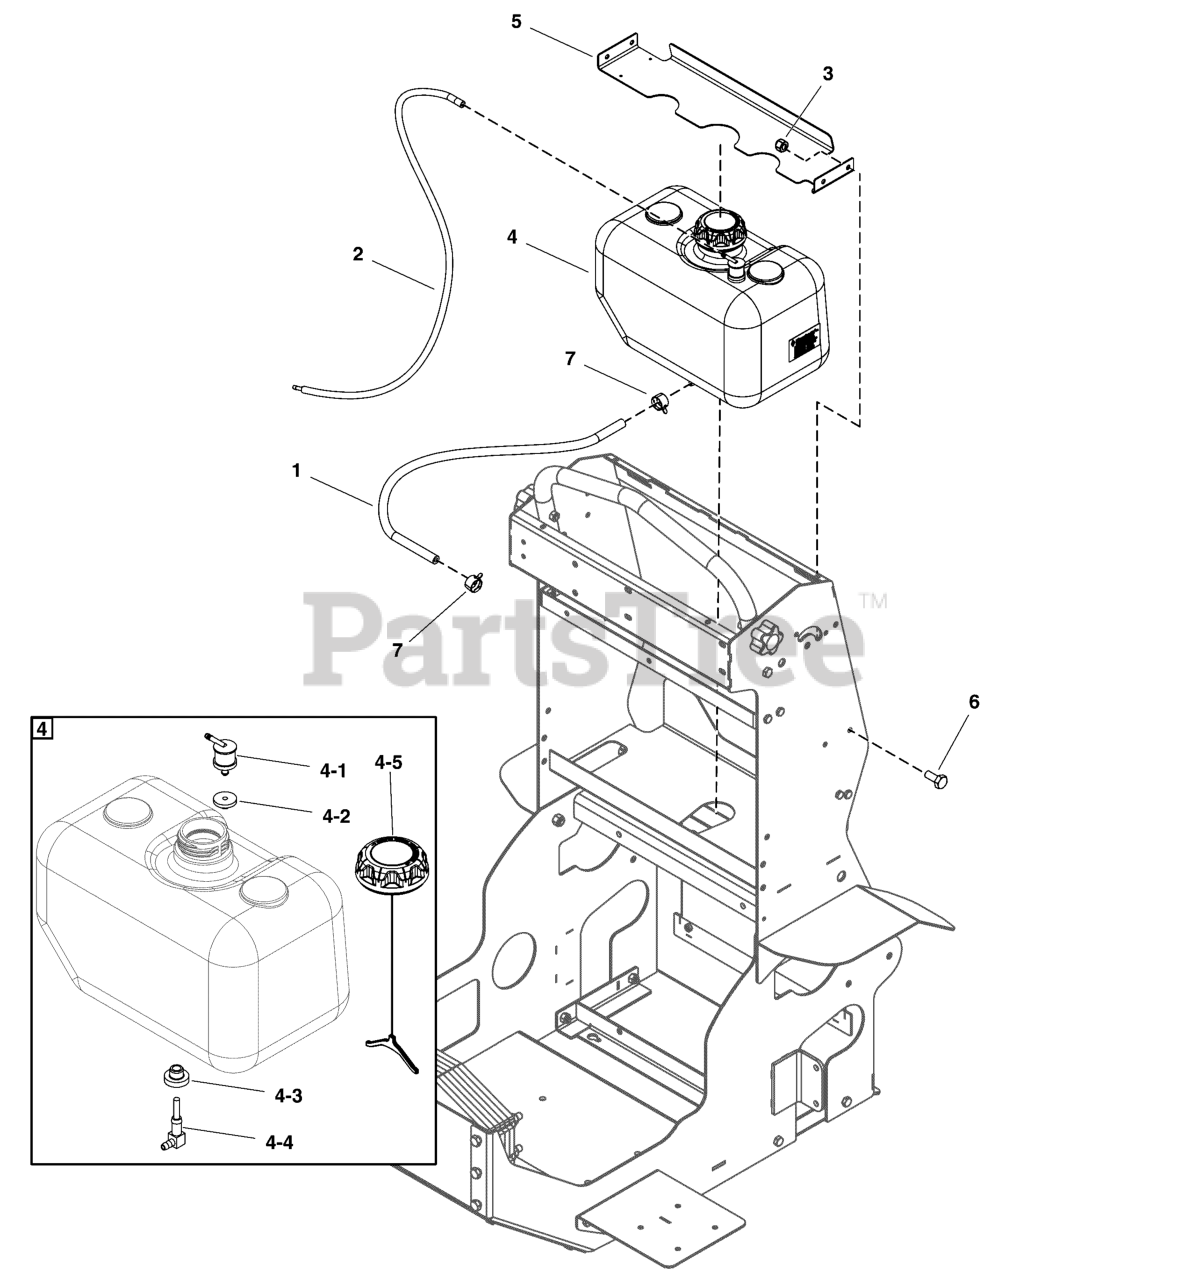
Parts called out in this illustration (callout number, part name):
1	1/4" Fuel Line, 14" Long
2	HOSE, FUEL VENT EPA 3/16" ID
3	NUT-HEX-NYLK, .250"-20 SS188
4	TANK, FUEL 2.5 GAL EPA/CARB
4-1	VALVE, SLOSH (C0155)
4-2	GROMMET, SLOSH VALVE (C0156)
4-3	GROMMET, VALVE, FUEL TANK (B0142)
4-4	FITTING, FUEL TANK (B0115)
4-5	CAP, FUEL, EPA (C0139)
5	BRACKET, FUEL TANK HOLD DOWN
6	SCR-CAP, HEX .250"-20 X .625" SS188
7	CLAMP, FUEL LINE 0.50"
